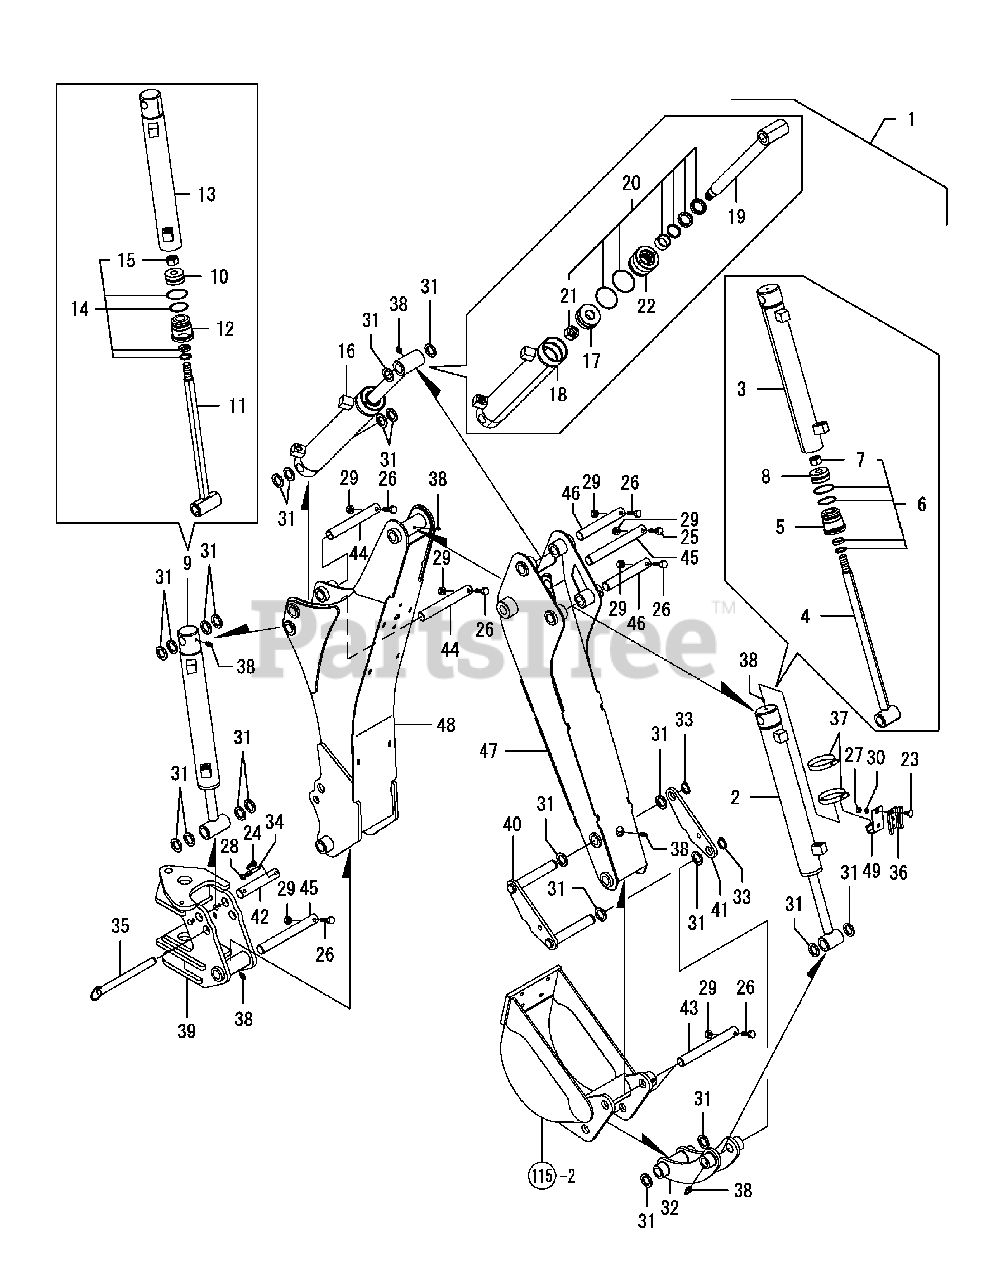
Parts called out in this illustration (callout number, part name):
1	BACKHOE KIT
2	CYLINDER, 2X13-1/8
6	SEAL REPAIR KIT
9	CYLINDER, 2X12-3/8
14	SEAL REPAIR KIT
16	CYLINDER, 2-1/2X11
20	SEAL REPAIR KIT
23	BOLT, CARR 31X75
24	BOLT, HEX 31X112
26	BOLT, HEX 38X200
28	NUT, LOCK NF 31
29	NUT, LOCK NF 38
30	WASHER, LOCK 31
31	MACH BUSH, 150
33	RETAINING RING
38	GREASE, FITTING
49	SMV SOCKET MOUNT
